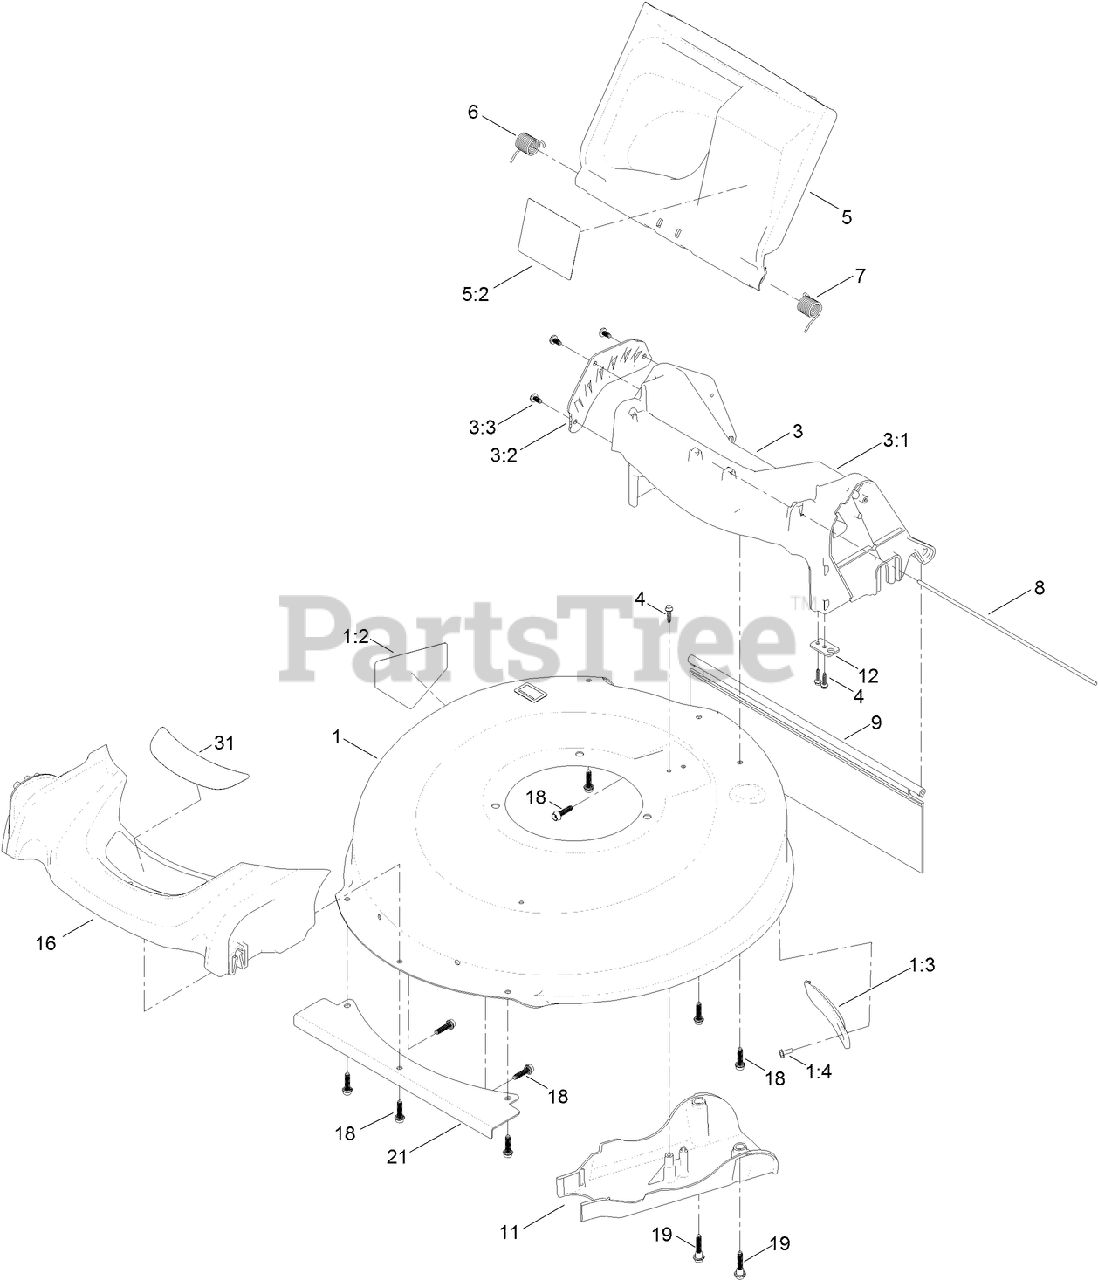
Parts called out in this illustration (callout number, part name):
1	HOUSING ASM
1:2	DECAL-DANGER
1:3	COVER-BELT
1:4	SCREW-TAPTITE
3	CHUTE ASM
3:1	CHUTE
3:2	PLATE-HOC
3:3	SCREW-PLASTIC TPH
4	SCREW-HWH
5	REAR DEFLECTOR ASM
5:2	DECAL-WARNING
6	SPRING-TORSION
7	SPRING-TORSION
8	ROD-DOOR
9	SHIELD-TRAILING
11	COVER-BELT
12	BRACKET-CABLE
16	BUMPER
18	SCREW-FLANGE, PLASTIC
19	SCREW-SHOULDER, HHF
21	SHIELD-FRONT
31	DECAL-DECK
